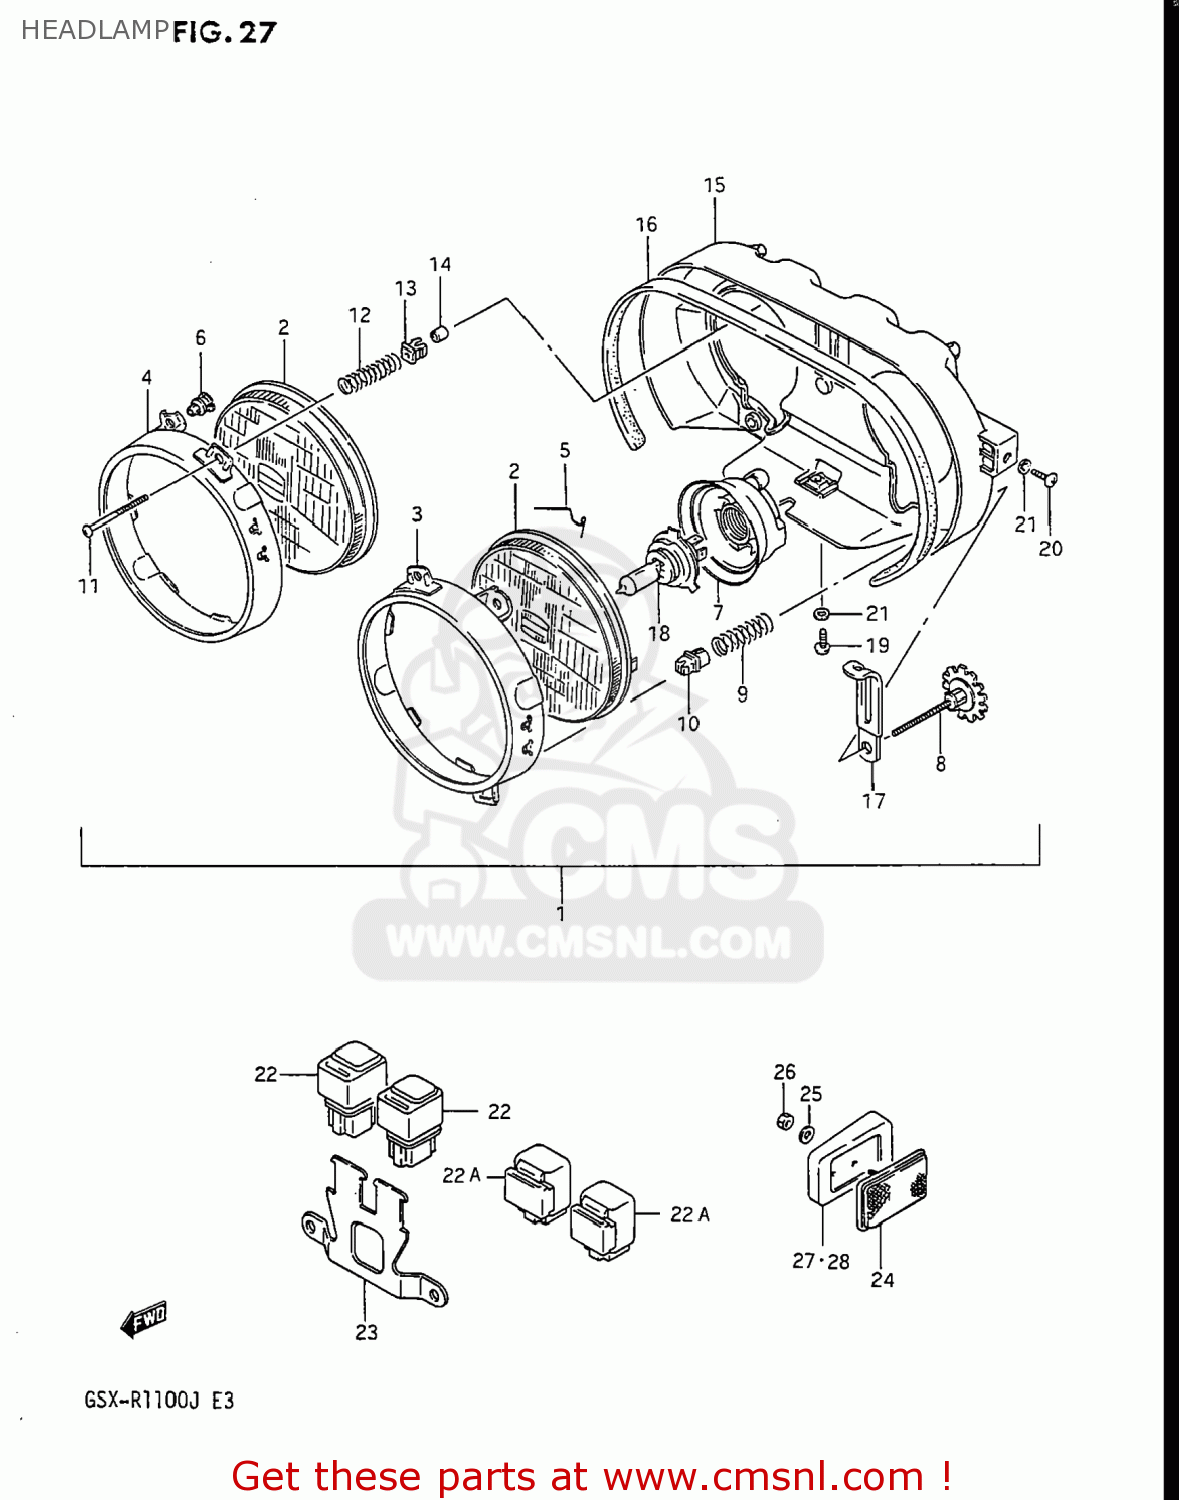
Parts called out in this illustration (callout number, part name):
1	HEADLAMP ASSY
2	LAMP UNIT
3	RING,RETAINING,LEFT
4	RING,RETAINING,RIGHT
5	SPRING
6	SCREW,SPHERICAL
7	COVER,SOCKET
8	SCREW,ADJUSTER
9	SPRING
10	NUT
11	SCREW,ADJUSTER
12	SPRING
13	NUT
14	CAP,SCREW
15	HOUSING,HEADLAMP
16	GASKET (NAS)
17	CLAMP
18	BULB(12V60/55W,H4)
19	SCREW
20	SCREW
21	WASHER,LOCK
22	RELAY, ANTINOSE DIVE FORK
22A	RELAY ASSY,HEADLAMP
23	BRACKET,HEADLAMP RELAY
24	REFLEX REFLECTOR ASSEMBLY
25	WASHER,5MM
26	NUT
27	SPACER,FRONT SIDE,REAR,RIGHT
28	SPACER,FRONT SIDE,REAR,LEFT
